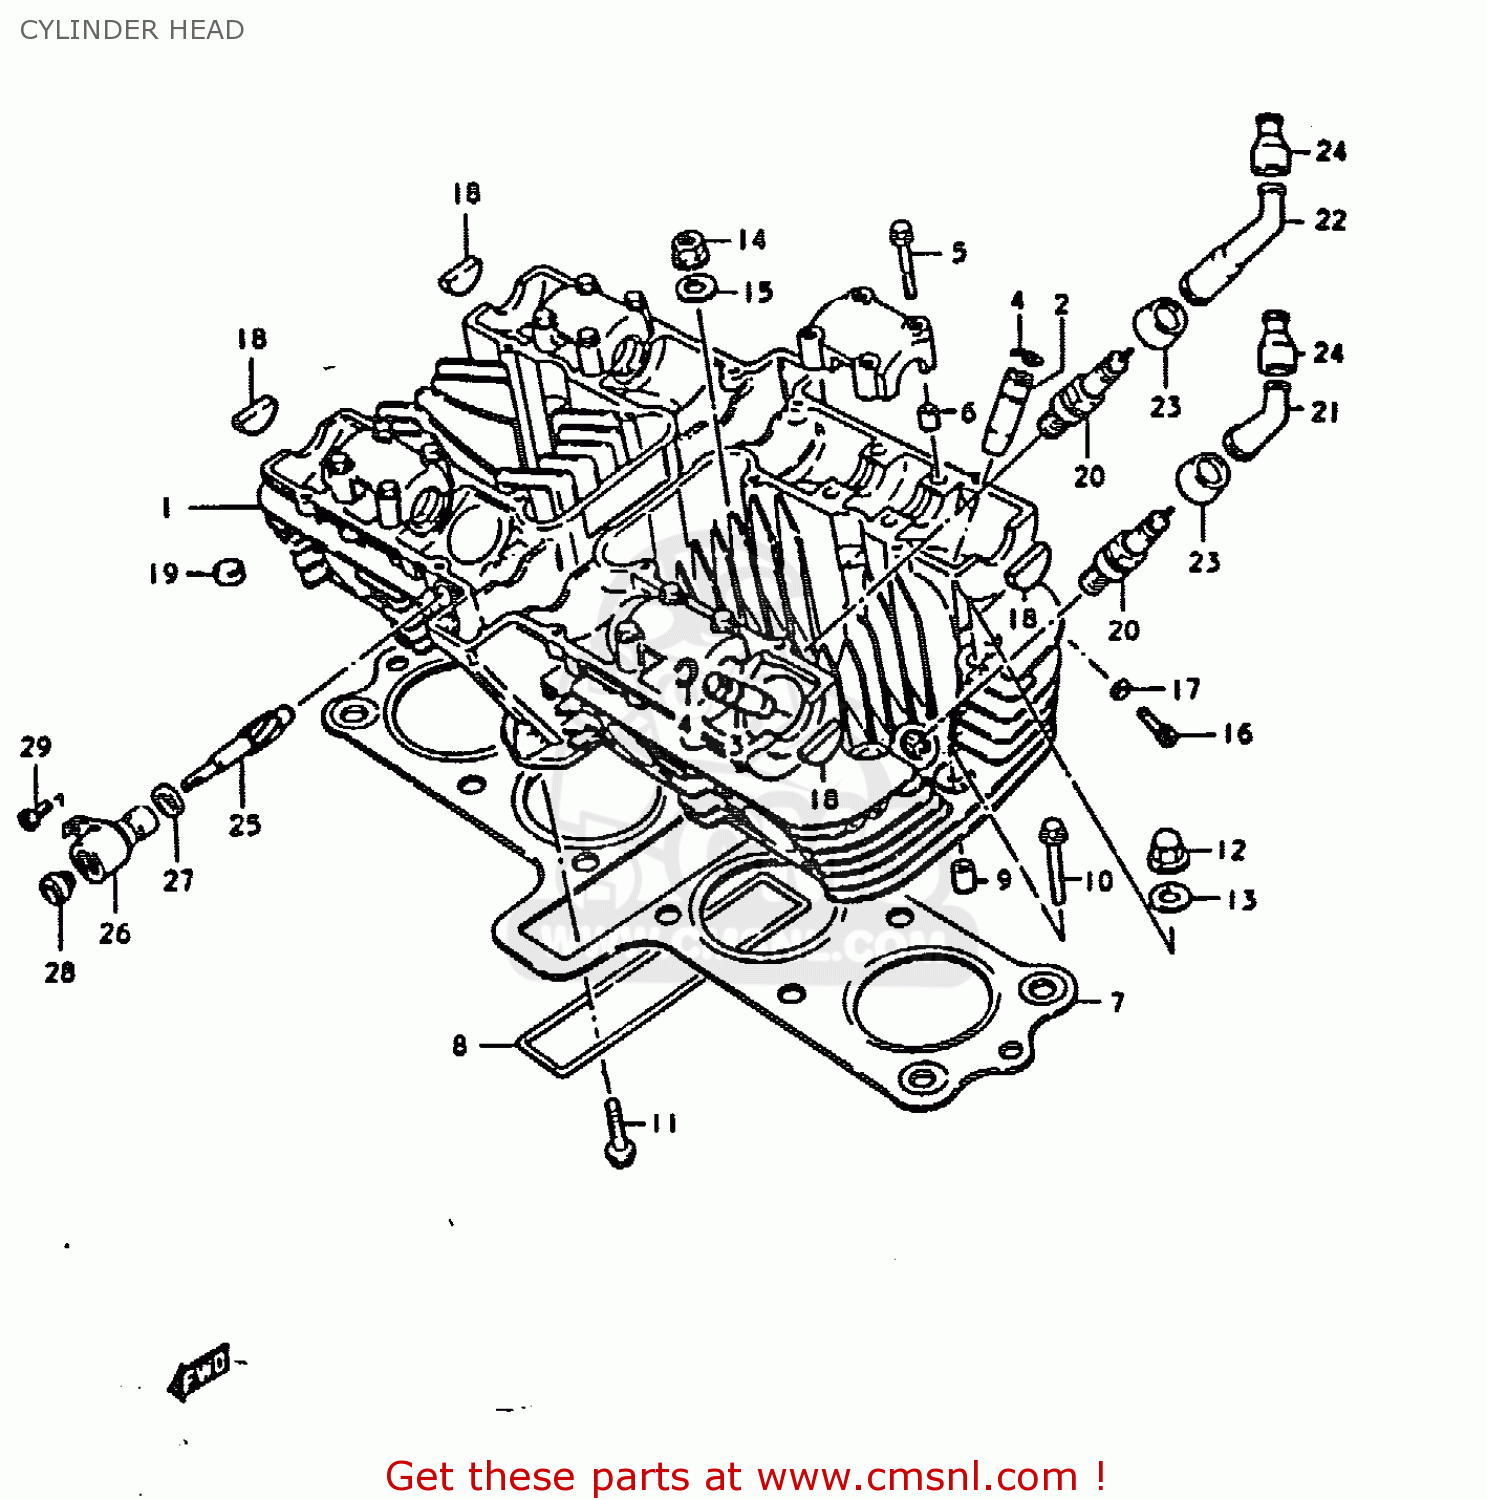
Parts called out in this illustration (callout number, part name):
1	HEAD ASSEMBLY,CYLINDER
2	GUIDE,VALVE
3	GUIDE,VALVE
4	RING,SNAP
5	BOLT(6X39)
6	PIN(6.2X8X11)
7	GASKET,CYLINDER HEAD (MCA)
8	O RING(D:3,ID:26X157)
9	PIN
10	BOLT,UNDER
12	NUT
13	GASKET(10.5X22X2) (NAS)
14	NUT
15	WASHER(10.5X22X2.3)
16	BOLT
17	GASKET(5.3X9.3X1.2) (NAS)
18	PLUG
19	PAD
20	PLUG,SPARK
21	CAP,SPARK PLUG
22	CAP ASSY,SPARK PLUG
23	SEAL,SPARK PLUG
24	SEAL,SPARK PLU
25	GEAR,TACHOMETER DRIVEN
26	SLEEVE,TACHOMETER DRIVE GEAR
27	SEAL,TACHOMETER DRIVEN
28	SEAL
29	SCREW(5X12)
